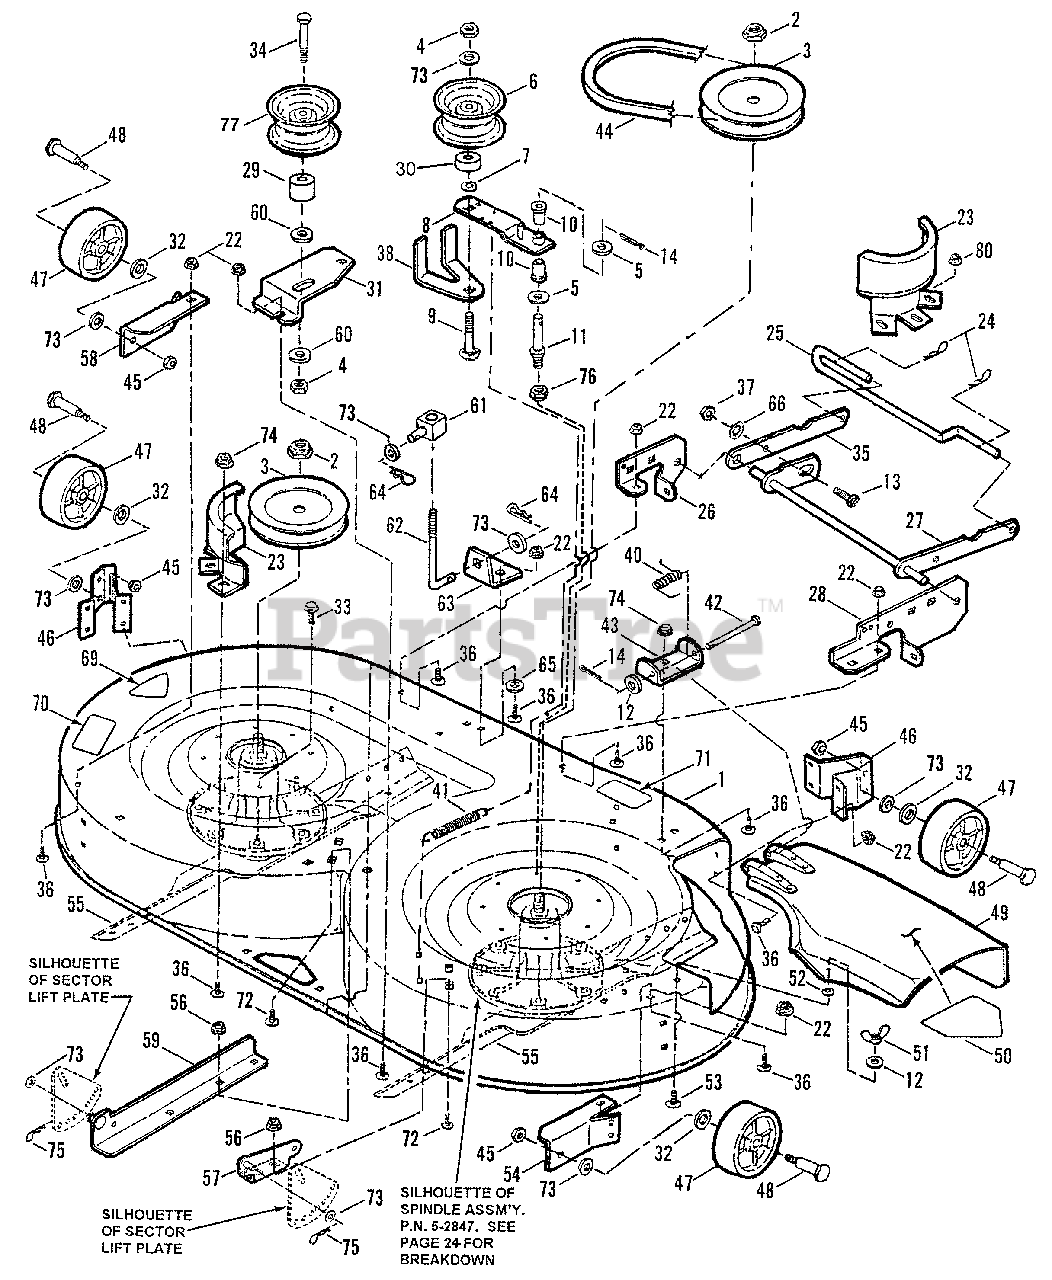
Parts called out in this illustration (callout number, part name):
1	WELDMENT Deck, 38" Cutting
2	NUT, 5/8-16 Hex Nyloc
3	PULLEY, Spindle 5.5" O.D.
4	NUT, 3/8-16 Hex Nyloc
5	WASHER, 3/8" Flat
6	PULLEY,Flat Idler 4-1/8"
7	RETAINER, 3/8 Bolt
8	WELDMENT, Idler Arm
9	BOLT, 3/8-16 x 2-3/4" Short Neck Carriage, Grade 5
10	BUSHING, Flange
11	STUD, Idler
12	WASHER,11/32 Flat
13	BOLT, 3/8-16 x 1-1/4" Sq. Neck Carriage, Grade 5
14	COTTER-PIN, 3/32 x 3/4"
22	NUT, 5/16-18 Hex Flange Lock Grade 5
23	GUARD, Belt
24	PIN, Hair 5/8"
25	PIN, Deck Hanger
26	BRACKET, Front Lift Arm (Left)
27	LIFT, Front Arm
28	BRACKET, Front Lift Arm (Right)
29	SPACER, 13/32 x 1-1/2 x 7/8
30	SPACER, 13/32 x 1-1/8 x 5/8
31	BRACKET, Fixed Idler
32	WASHER, 1/2 Flat (4)
33	SCREW, 3/8-16 x 3/4" Self Tapping
34	CAPSCREW, 3/8 -16 x 2.5 Hx. Hd. Grade 5
35	ARM, Front Lift
36	BOLT, 5/16-18 x 5/8" Short Neck Carriage Grade 5
37	NUT, 3/8-16 Hex Grade B or 5
38	GUIDE, Belt
40	SPRING, Chute Deflector Hinge
41	SPRING, Blade Brake
42	PIN, 5/16 x 3-3/16" Clevis
43	HINGE, Chute Deflector
44	BELT, Drive, 38" Cutting Deck, 96.0" E.L. HA
45	NUT, 3/8-24 Hex Ctr. Lock
46	BRACKET, Gage Wheel, Front
47	WHEEL, Gage
48	BOLT, 3/8-24 x 5/8" Shoulder
49	ASSEMBLY, Chute Deflector
50	DECAL, Danger
51	NUT, 5/16-18 Wing
52	RETAINER, 5/16 Bolt
53	BOLT, 5/16-18 x 3/4" Short Neck Carriage, Grade 5
54	BRACKET, Wheel (Right Side)
55	BLADE, 19-1/2"
56	NUT, 3/8-16 Hex Flange Lock
57	BRACKET, Rear Deck Lift (Right Side)
58	BRACKET, Wheel (Left Side)
59	BRACKET, Rear Deck Lift (Left Side)
60	WASHER, 13/32" I.D. x 1 1/2 O.D. x 1/8"
61	SWIVEL, Lift
62	BOLT,3/8-16, "J"
63	BRACKET, Angle (Front)
64	PIN, Hair #13
65	WASHER, 7/16 Flat
66	WASHER,13/32 I.D. Cone
69	DECAL, 38"
70	DECAL - CAUTION (Rotating Blades)
71	DECAL - CAUTION
72	BOLT, 3/8-16 x 3/4" Carriage Gr. 2
73	WASHER, 3/8" Flat
74	NUT, 5/16-18 Hex Flg Lk, Gr. 5
75	PIN, Hair, 3/32 x 1-1/2"
76	NUT, 5/16-24 Hex Lock Grade C
77	PULLEY, Flat Idler 3.25"x1.75"
